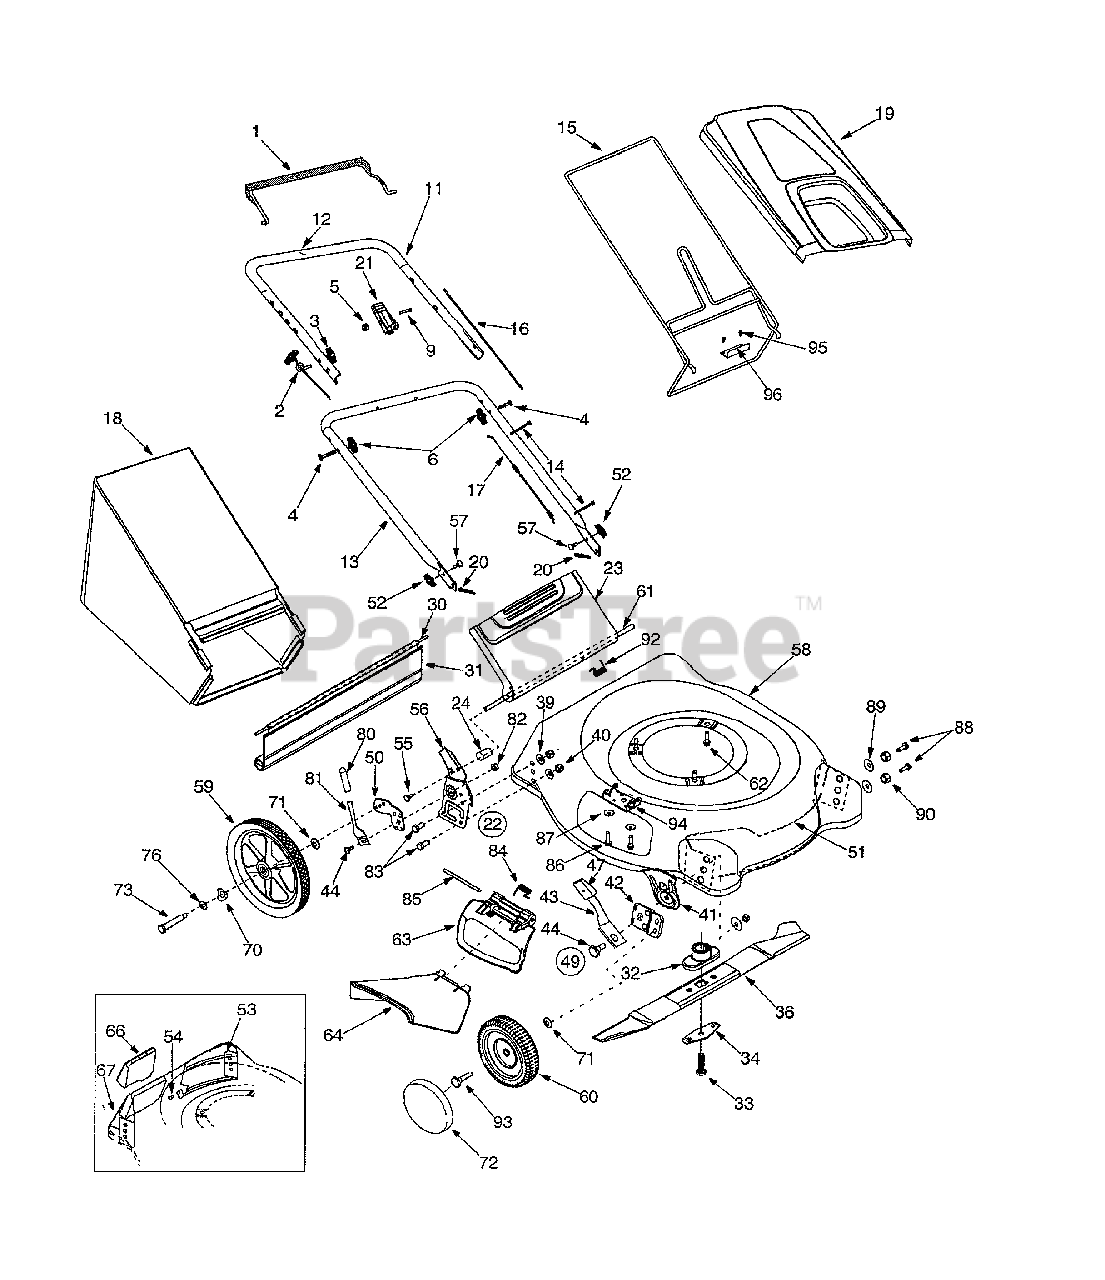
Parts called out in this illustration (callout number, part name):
1	Deluxe Control Handle
2	Rope Guide
3	Handle Knob
4	Curved Hd. Bolt 5/16-18 x 2"
5	Hex L-Nut 1/4-20 Thd.
6	Hand Knob
9	Screw 1/4-20 x 1.31
14	Cable Tie
16	Control Cable 39"
16	Control Cable 51"
17	Throttle Cable 60"
17	Throttle Cable 42"
18	Grass Bag w/o logo
18	Grass Bag w/ logo, Yellow
18	Grass Bag w/ logo, Red
19	Hard Top w/ logo
19	Hard Top w/o logo
20	Internal Cotter Pin
21	Throttle Housing w/o Lever
22	Handle Bracket Assembly - RH
30	Wire Rod
31	Rear Flap
32	Blade Adapter Kit
33	Hex Bolt 3/8-24 x 1.5"
34	Blade Bell Support
36	Mulching Blade
39	Bell Washer .39" I.D. x 1.38"
40	Hex Lock Nut 3/8-16
41	Height Adj. Plate
43	Spring Lever: Front Wheel
44	Shoulder Bolt .5" Dia. x .357"
47	Spring Lever Knob
49	Height Adj. Assembly Comp - RH
49	Height Adj. Assembly Comp - LH
50	Pivot Bar - RH
50	Pivot Bar - LH
54	Torx Mach. AB-Tap
55	Hex Washer Screw 1/4-14
56	Handle Bracket Assembly - RH
56	Handle Bracket Assembly - LH
57	Carriage Bolt, 1/4-20
59	Rear Wheel Ass’y. 14 X1.8
60	Front Wheel Ass’y. 8 X 2
60	Front Wheel Ass’y 8 x 1.75
60	Front Wheel Ass’y 8 X1.7
60	Front Wheel Assembly 8 X 1.8
61	Chute Door Pivot Rod
62	Sems Screw TT 3/8-16 X 1
63	Mulching Plug
64	Chute Deflector
66	Rear Mulch Plug
70	Wave Washer
71	Spring Washer
72	Hub Cap
73	Rear Axle Bolt
76	Flat Washer
80	Foam Grip
81	Height Adj. Lever
82	Hex Flange Lock Nut 3/8-16
83	Hex Cap Screw 3/8-16 X 1.0
84	Torsion Spring
85	Hinge Pin
87	Bell Washer .265 x .75 .062
88	Hex Screw 3/8-16 x .75
89	Bell Washer .39 x 1.13 X .062
90	Hex Nut 3/8-16
92	Torsion Spring
93	Front Axle Bolt
95	Hex Screw 1/4-14 x .625
